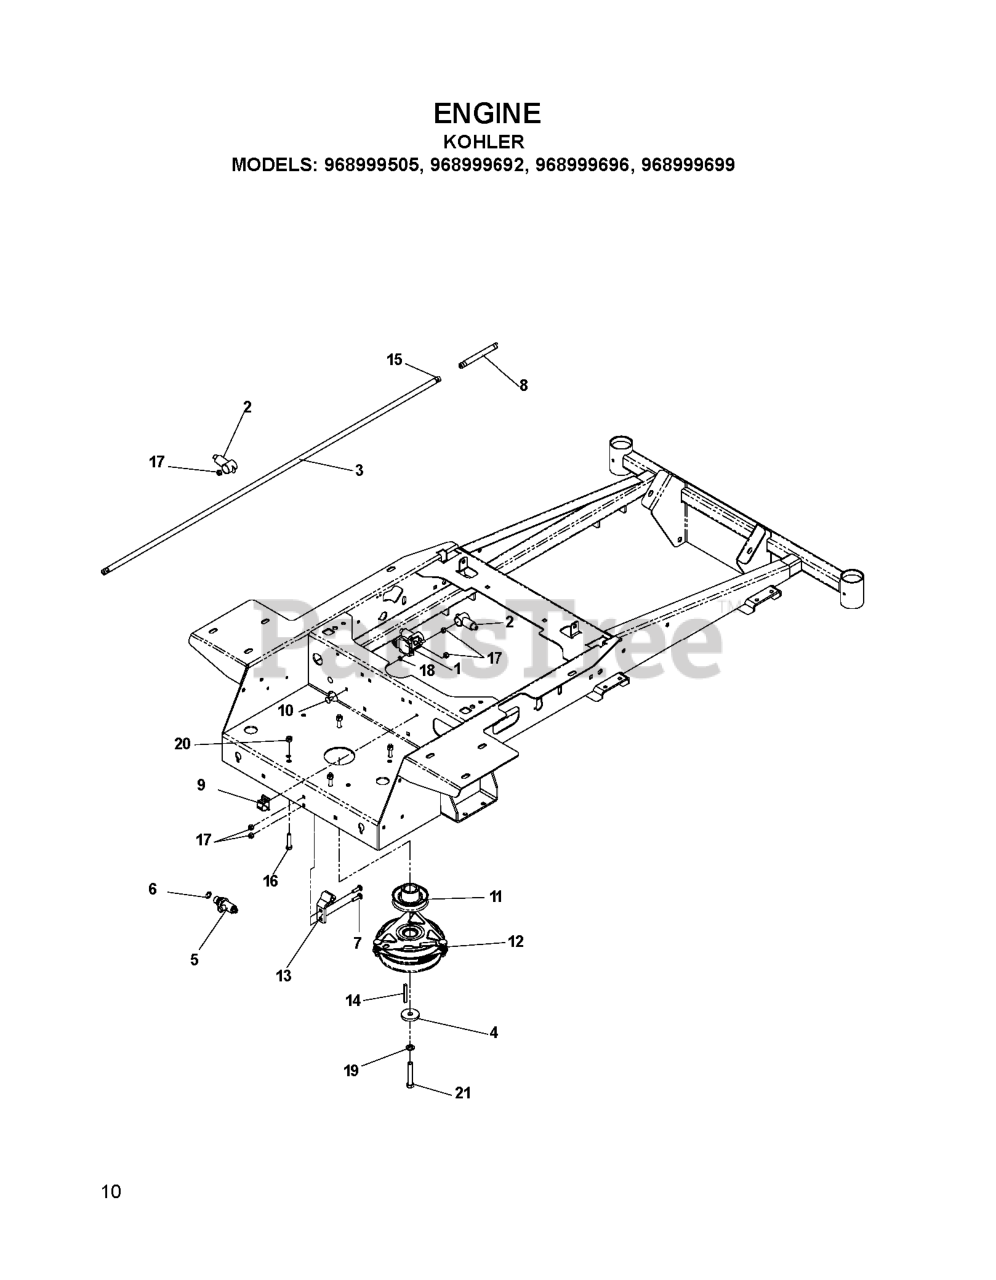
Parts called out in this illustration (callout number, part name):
4	SPINDLE WASHER
5	OIL DRAIN FITTING
6	WASHER 5/16 EXT STAR
7	RHSNB, 1/4-20 X 1, GR5
8	FUEL LINE 5"
9	PUSH-MOUNT WIRE CLIP
10	RHSSNB, 1/4-20X5/8
11	PULLEY, DRIVE
12	CLUTCH, 150 FT/LBS
13	TIE DOWN, CLUTCH
14	KEY 1/4 SQ X 2
15	HOSE CLAMP
16	BOLT 3/8-16 X 1.0
17	NUT.1/4-20.HEX.NYLOC.ZD
18	WASHER 1/4 INT TOOTH
19	WASHER 7/16 LOCK
20	NUT 5/16 NYLOC
21	HCS 7/16F X 1 1/2
22	TIE, PLASTIC
23	HCS 5/16C X 3/4
24	WASHER 5/16 FLAT
